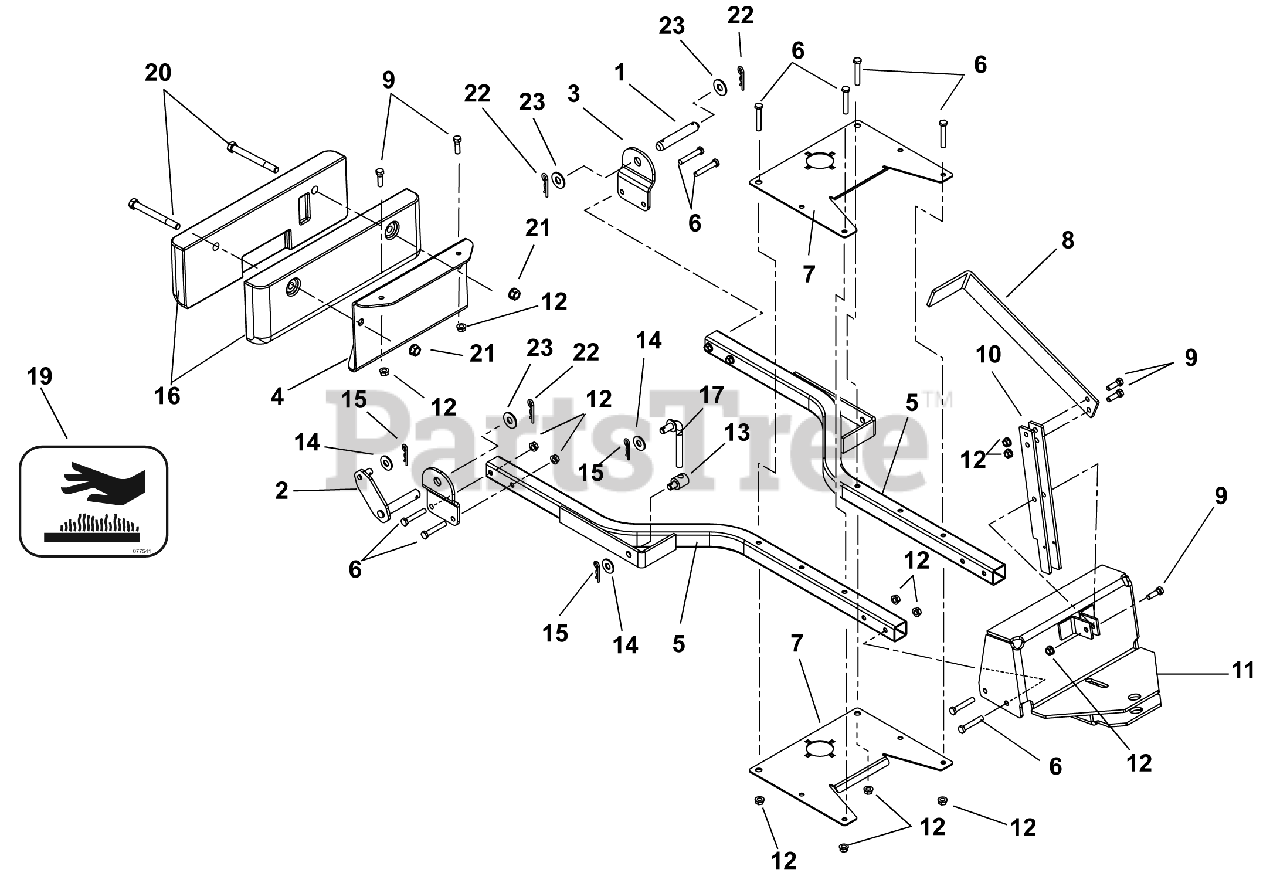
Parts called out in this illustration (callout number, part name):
1	PIN, REAR LIFT PIVOT (LEFT)
2	WDMT, REAR LIFT PIVOT (RIGHT)
3	BRKT, PIVOT
4	BRKT, WEIGHT
5	WMT, SUB-FRAME TUBE
6	@BLT-HEX .38-16X2.25 GR5 YWZC
7	PLATE,SUB-FRAME
9	@BLT-HEX .38-16X1.25 GR5 YWZC
11	YOKE,BLADE MOUNT
12	@NUT-LK-TOP-FLG .38-16 YWZC
13	TRUNNION-.50
14	WSHR-FL-STL .531X1.250X.10 YWZ
15	PIN, HAIR, EXT - #16 YWZC
16	WEIGHT, CAST IRON
17	LIFT LINK WELDMENT
18	ASSY,WHEEL & TIRE 18X6.5 S-HOG
19	DECAL, HOT SURFACE
20	@BLT-HEX .50-13X5.00 GR5 YWZC
21	@NUT-LK-TOP-FLG .50-13 YWZC
22	BOLT, DIN933 M6X22 HEX
23	@WSHR-FL-STL.812X1.50X.135YWZC
